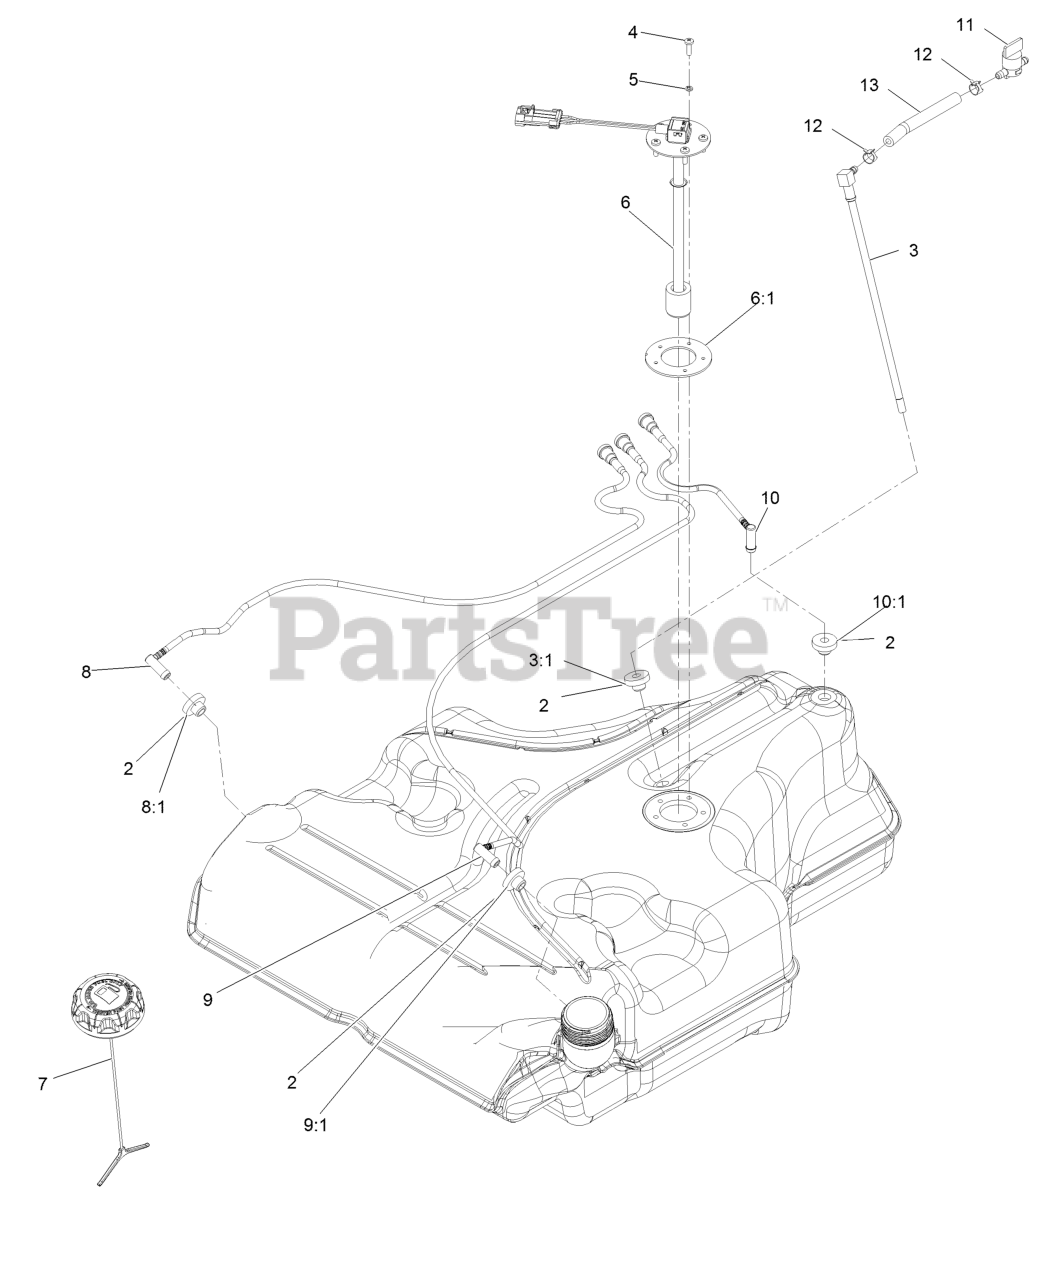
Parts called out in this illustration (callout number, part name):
2	Bushing
3	Fuel Line Kit (With Grommet)
3:1	Bushing
4	Screw-PPH #10-24 X 5/8
5	Washer-Lock 3/16
6	Sender-Level, Fuel (W/Gasket)
6:1	Gasket-Sender
7	Cap-Fuel, Ratcheting
8	RH Vent Line Kit (With Grommet)
8:1	Bushing
9	LH Vent Line Kit (With Grommet)
9:1	Bushing
10	Rear Vent Line Kit (With Grommet)
10:1	Bushing
11	Valve-Fuel
12	Clamp-Hose
13	Hose-Fuel
